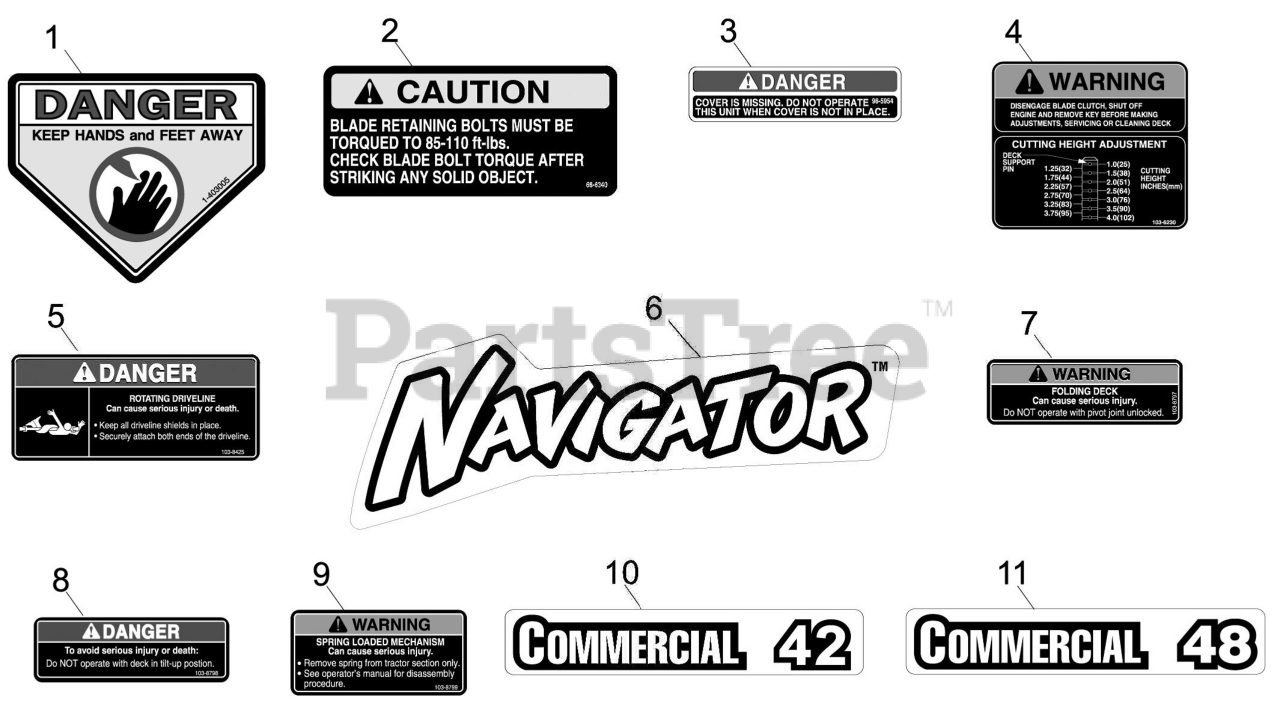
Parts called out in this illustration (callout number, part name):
1	DECAL-DANGER
2	DECAL-TORQUE
3	DECAL-COVER, MISSING
5	DECAL-DRIVELINE
6	DECAL,NAVIGATOR MODEL
7	DECAL-FOLDING DECK
8	DECAL-DANGER
9	DECAL-SPRING
10	DECAL,COMMERCIAL 42
11	DECAL,COMMERCIAL 48
